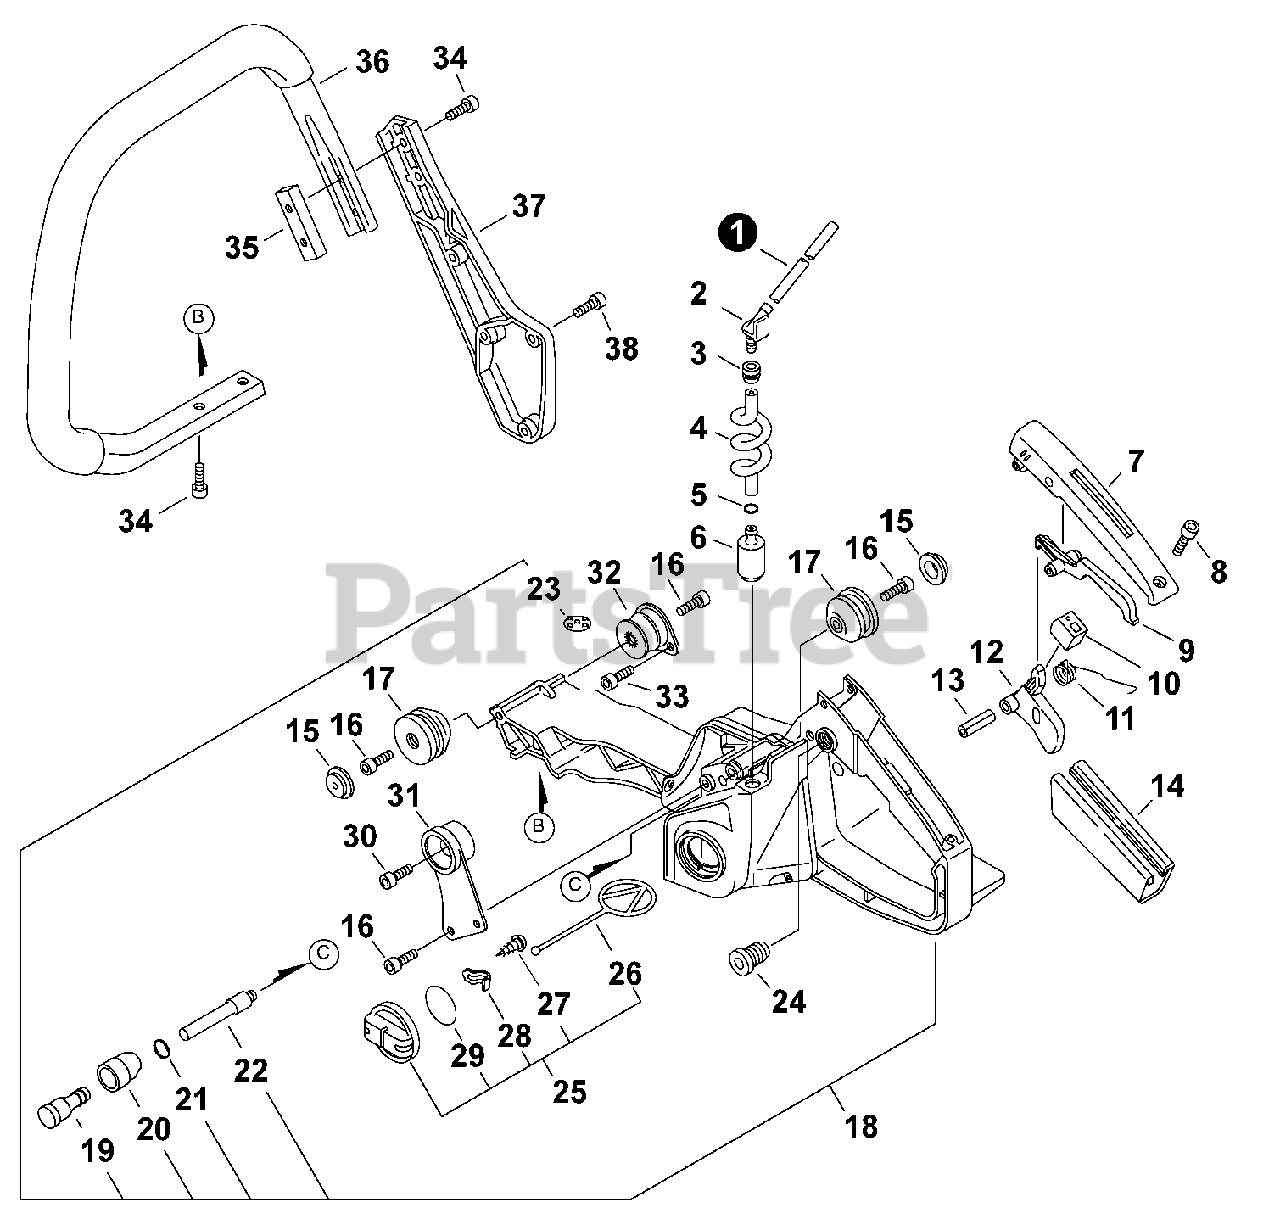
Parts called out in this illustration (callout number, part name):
1	PIPE
2	CONNECTOR, PIPE
3	GROMMET
4	PIPE, FUEL
5	CLIP Ø6.5MM
6	FILTER, FUEL
7	COVER, HANDLE
8	BOLT 4×14
9	LEVER, THROTTLE LOCKOUT
10	CUSHION, THROTTLE
11	SPRING, THROTTLE RETURN
12	TRIGGER, THROTTLE
13	PIN, SPRING 5×25
14	GRIP, HANDLE
15	CAP, CUSHION
16	BOLT 5×14
18	HANDLE ASSY, REAR
19	VENT ASSY
20	HOLDER, VENT
21	CLIP 5.5
22	PIPE 3×5×55
25	CAP ASSY, FUEL
26	CONNECTOR, CAP L=60mm
27	SCREW, TAPPING 3×8
28	RETAINER, CONNECTOR
29	O-RING 29
30	BOLT 5×20
33	BOLT 4×10
34	BOLT 5×20
36	HANDLE, FRONT
37	BRACKET, FRONT HANDLE
38	BOLT 5×20
